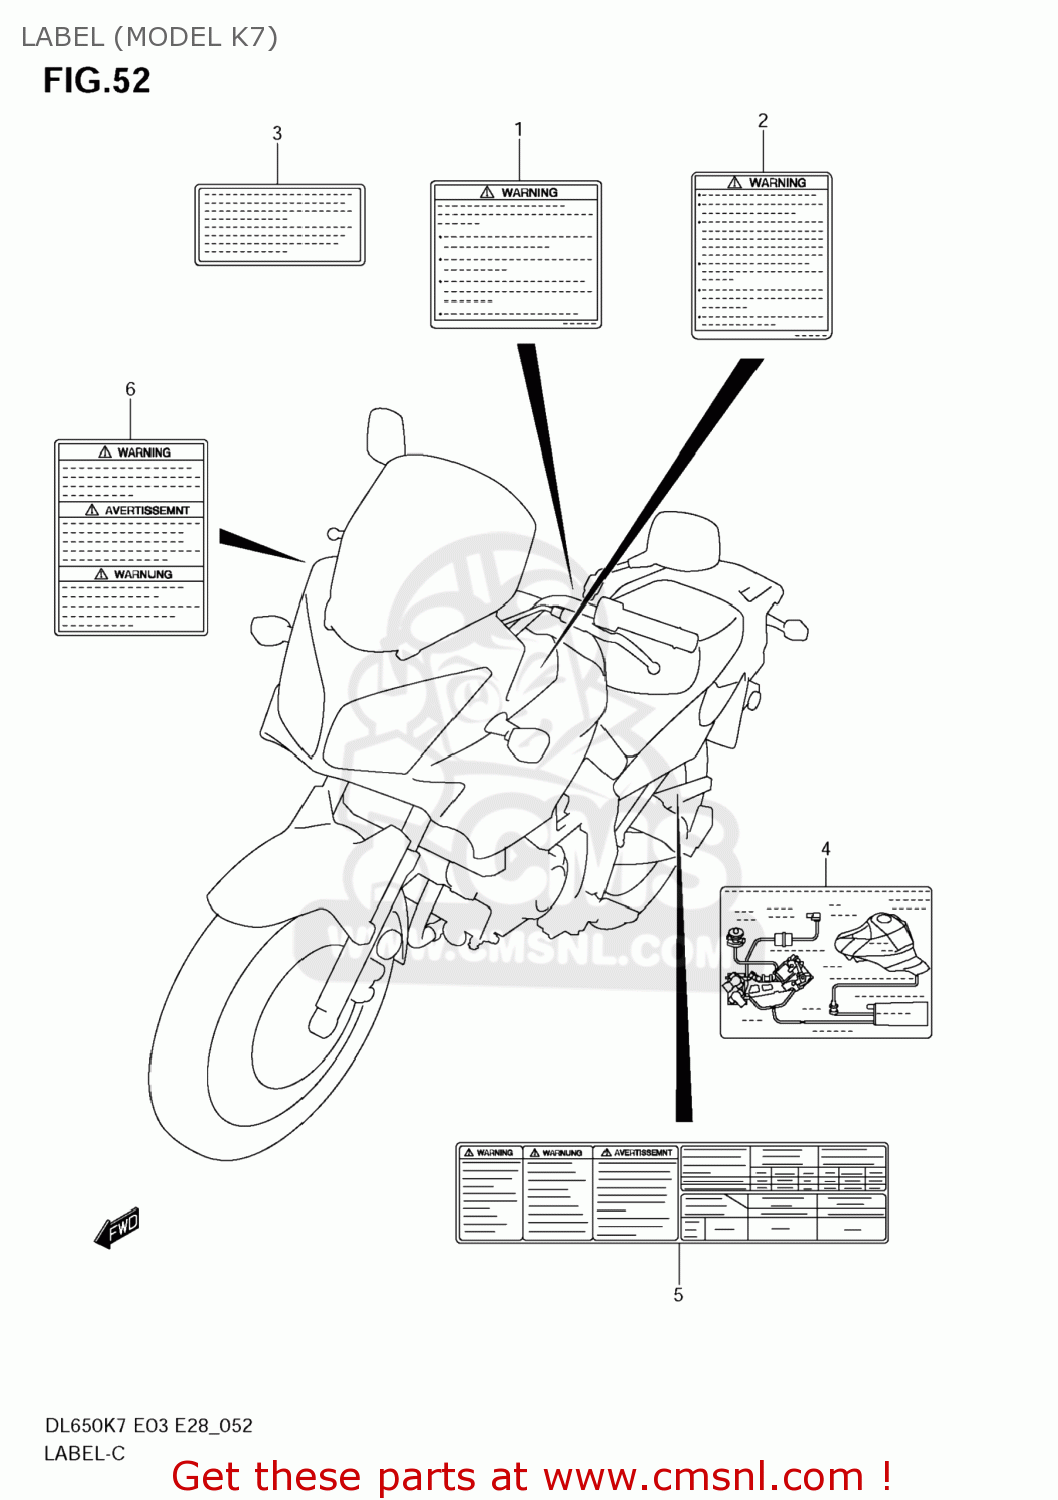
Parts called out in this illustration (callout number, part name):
1	LABEL,GENERAL WARNING
2	LABEL,SCREEN
3	LABEL,MANUAL NOTICE
4	LABEL, ROUTING
5	LABEL,TIRE INFORMATION
6	LABEL,WARNING STEERING
7	MANUAL,OWNER'S
